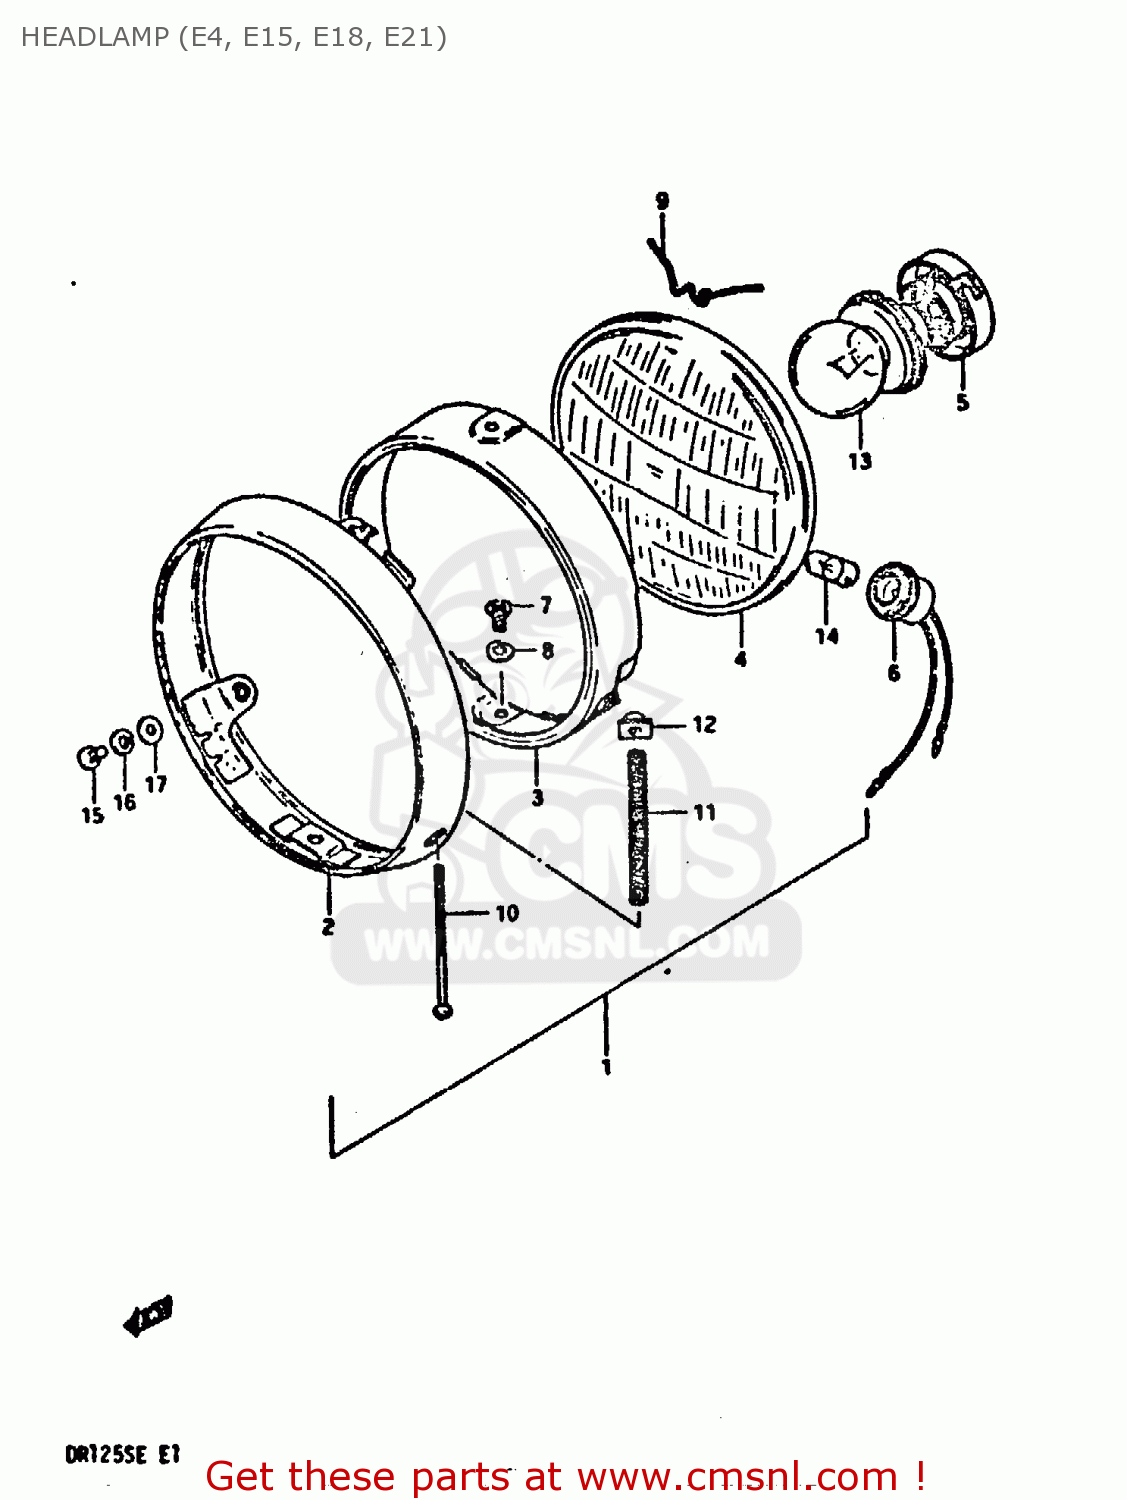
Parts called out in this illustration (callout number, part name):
1	HEADLAMP ASSY
2	RIM,HEADLAMP
3	RETAINER
4	UNIT
5	SETTER,BULB
6	SOCKET
7	SCREW
8	LOCK WASHER
9	SPRING
10	SCREW
11	SPRING
12	NUT
13	BULB(12V45/40W)
14	BULB(12V4W)
15	SCREW
16	LOCK WASHER
17	WASHER
